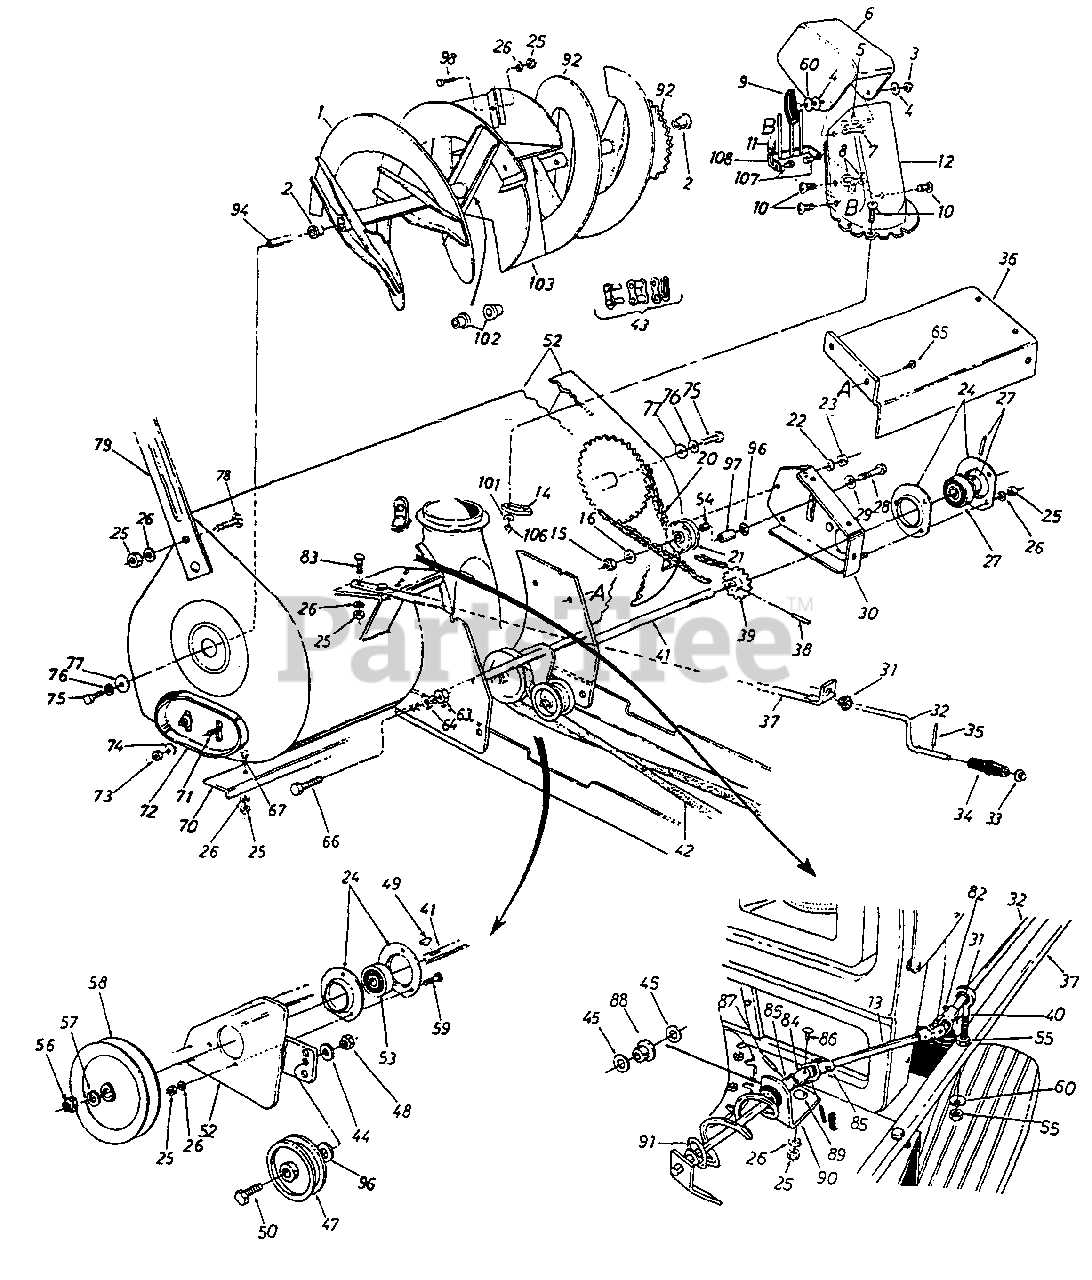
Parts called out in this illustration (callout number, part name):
3	Hex L-Nut 5/16-18 Thd.
4	Fl-Wash. .344" I.D.
5	Truss Mach. Scr. 5/16-18 x .75" Lg.
6	Upper Chute
7	Carriage Bolt 5/16-18 x 1.0" Lg.
8	Hex L-Nut 1/4-20 Thd.
9	Hand Knob
10	Truss Mach. Scr. 1/4-20 x .75" Lg.
11	Ext. Spring
12	Lower Chute
13	Chute Crank Extension Rod
14	Chute Flange Keeper
15	L-Nut 3/8-16 Thd.
16	Fl-Wash.
20	#420 Chain 1/2" Pitch x 77 Links
21	Plastic Idler 2" O.D.
22	L-Wash. 1/4" I.D.
23	Hex Nut 1/4-20 Thd.
24	Bearing Housing
25	Hex Nut 5/16-18 Thd.
26	L-Wash. 5/16" I.D.
27	Self-Aligning Bearing
28	Hex Bolt 3/8-16 x 1.75" Lg.
29	Belleville Wash. 3/8" I.D.
32	Chute Crank .375" Dia. x 34.5" Lg.
33	Push Nut 3/8" Rod
34	Knob (Black)
35	Roll Pin
39	14 Teeth Sprocket Ass'y.
40	Eyebolt 5/16-18 x 3.0" Lg.
41	Drive Shaft
42	"V"-Belt
43	Master Link for #420 Chain
44	L-Wash. 3/8" I.D.
45	Fl-Wash. .385" I.D. x .62" O.D.
47	Fl-Idler with Flanges
48	Hex Jam L-Nut 3/8-16 Thd.
49	#61 Hi-Pro Key 3/16 x 5/8 Dia.
50	Hex Bolt 3/8-16 x 1.75" Lg.
52	Spiral Housing Ass'y.
53	Self-Aligning Bearing
54	Sleeve Bearing .50" I.D.
55	Hex Nut 5/16-18 Thd.
56	Hex Nut 3/4-10 Thd.
57	L-Wash. 3/4" J.D.
58	"V"-Pulley .750" I.D. x 6" O.D.
59	Hex Sems Bolt 5/16-18 x .75" Lg.
60	Bell-Wash. .345" I.D. x .88" O.D.
63	Hex L-Nut 1/2-20 Thd.
64	L-Wash. 1/2" I.D.
65	Hex Self-Tap Scr. 1/4-20 x .5" Lg.
66	Hex Bolt 1/2-20 x 1.25" Lg.
67	Carriage Bolt 5/16-18 x .75"
73	Hex Jam Nut 3/8-16 Thd.
74	Belleville Wash. 3/8" I.D.
75	Hex Bolt 1/2-13 x 1.25" Lg.
76	Belleville Wash. 1/2" I.D.
77	Fl-Wash.
78	Carriage Bolt 5/16-19 x .62" Lg.
82	Cotter Pin
83	Hex Bolt 5/16-18 x 1.5" Lg.
84	Joint Block
85	Joint Bracket Ass'y.
86	Oval Head Rivet
87	Spring Pin Roll 1/8" Dia. x .75" ig.
88	Nylon Bushing
89	Carriage Bolt 5/16-18 x .75" Lg.
90	Chute Crank Bracket
91	Chute Crank Ass'y.
96	Flat Washer
97	Idler Spacer
98	Carriage Bolt 5/16-18 x .75" Lg.
101	Fl-Wash. 1/4" I.D.
102	Plastic Bushing
107	Shld. Nut 1/4-20 Thd.
